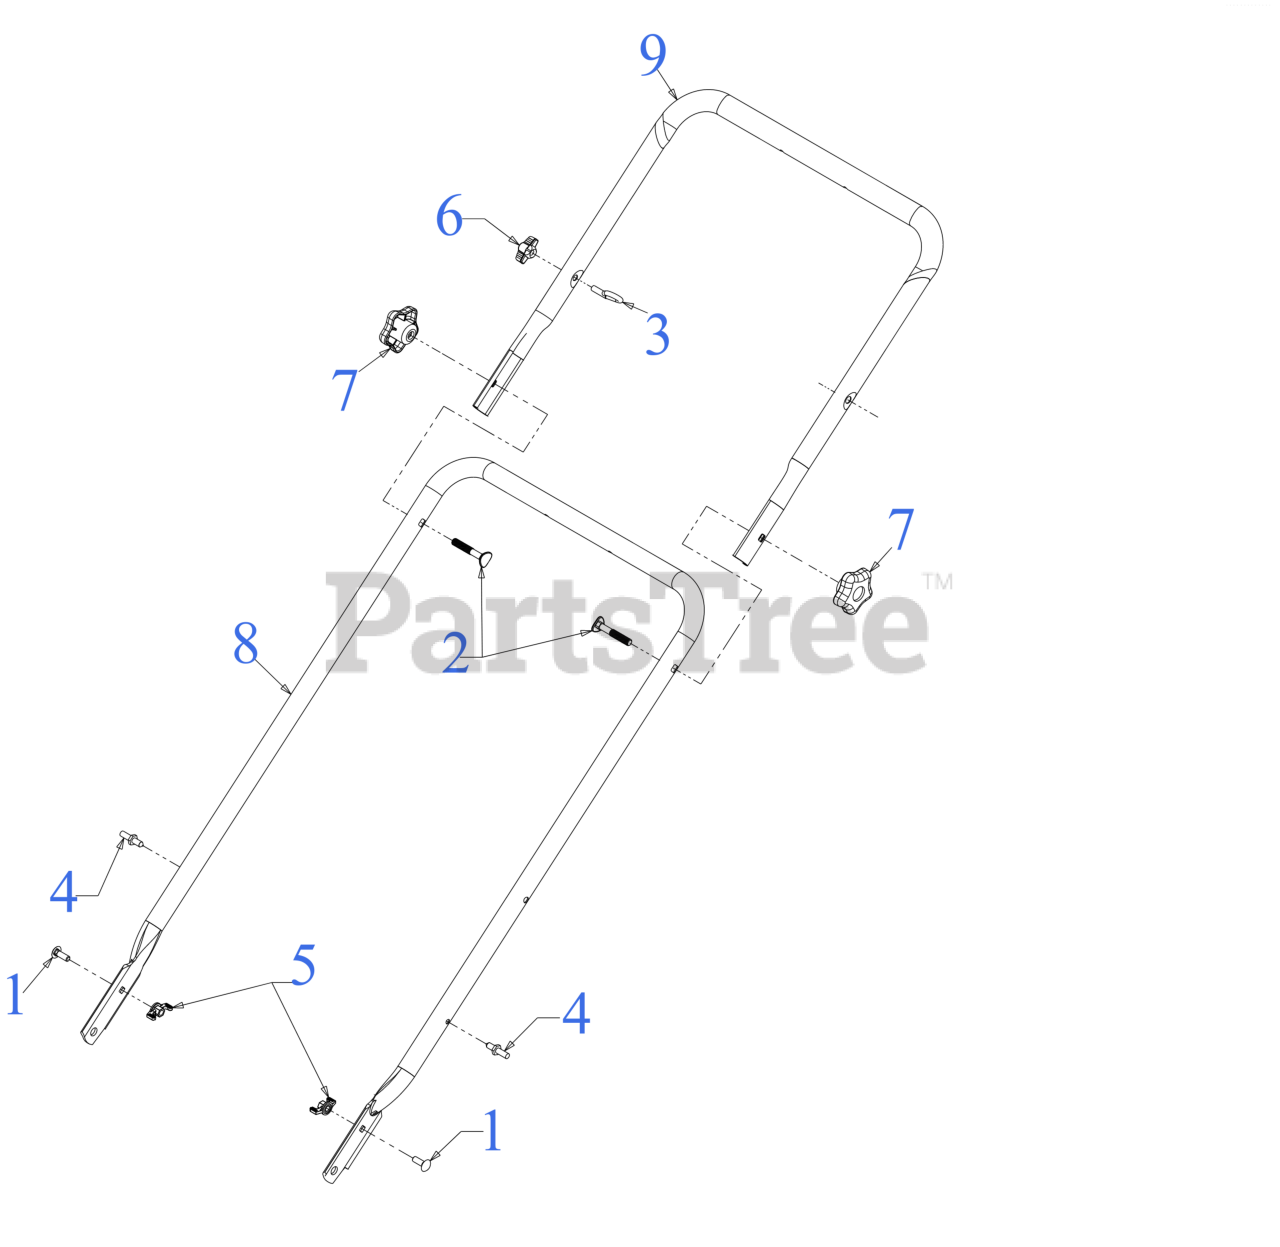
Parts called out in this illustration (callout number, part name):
1	SCREW 1/4-20 x .75 GR5
2	SCREW .312-18X2.0
3	EYEBOLT 1/4-20
4	BELT KEEPER PIN 1/4-20
6	HANDLE KNOB
7	STAR KNOB 5/16-18
